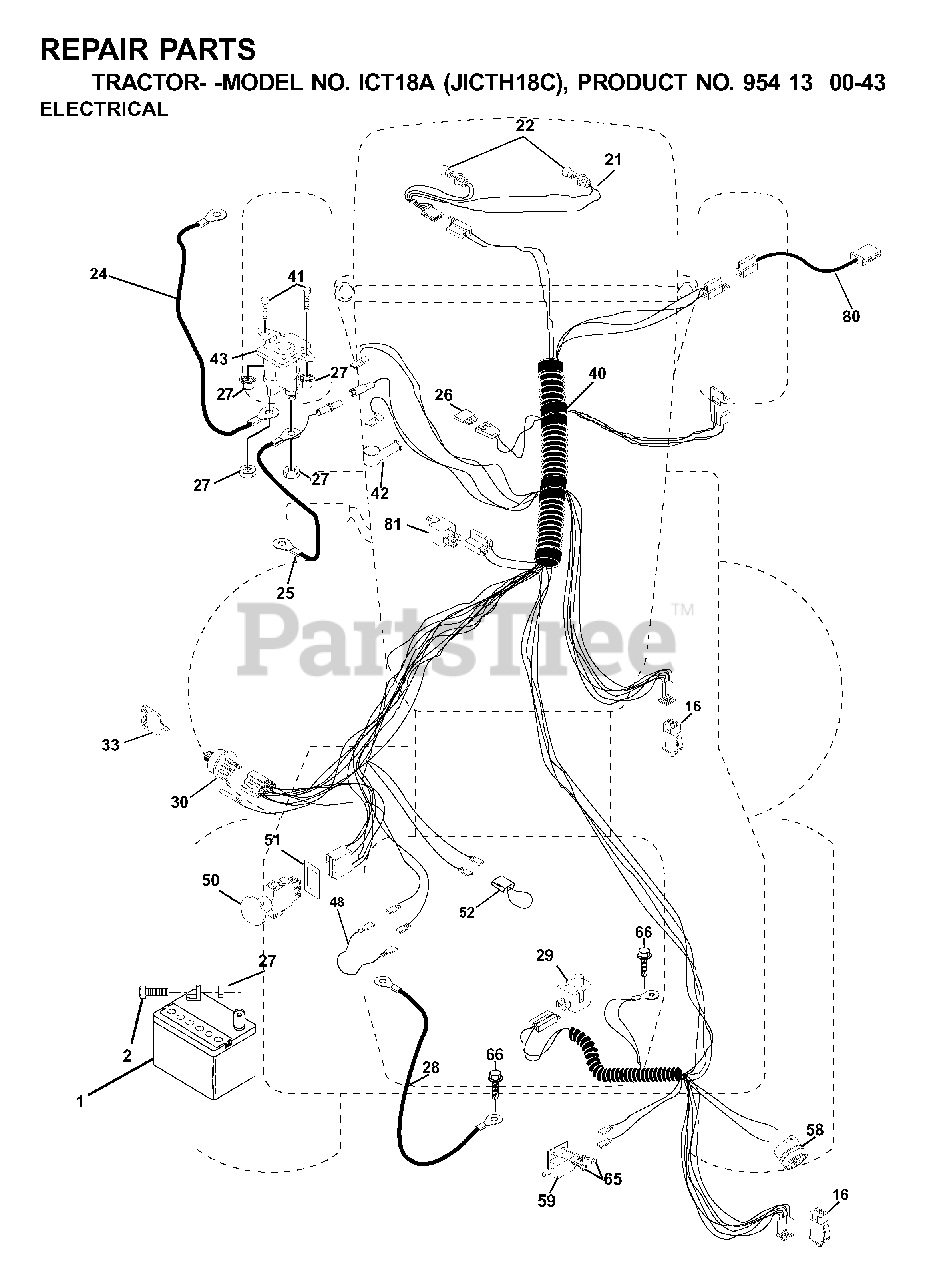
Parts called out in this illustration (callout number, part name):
1	BATTERY 12V .35 AMP
16	SWITCH INTERLOCK
21	HARNESS ASM, LIGHT W/4152J
22	LIGHTBULB
24	BATTERY CABLE GT
25	CABLE BATTERY
26	FUSE 20AMP
27	NUT
28	CABLE GROUND
29	PLUNGER SWITCH (COLOR:OLIVE)
30	IGNITION SWITCH
33	KEY MLD GEN DELTA
40	HARNESS IGN
42	TERMINAL COVER
43	REPL BY 532 1461-54
50	SWITCH.PTO.8.TERMINAL.
51	RETAINING RING
52	WIRE PROTECTION LOOP
58	BUZZER
66	SCREW LT
80	HARNESS, CLUTCH
81	RELAY.ASSY.T
